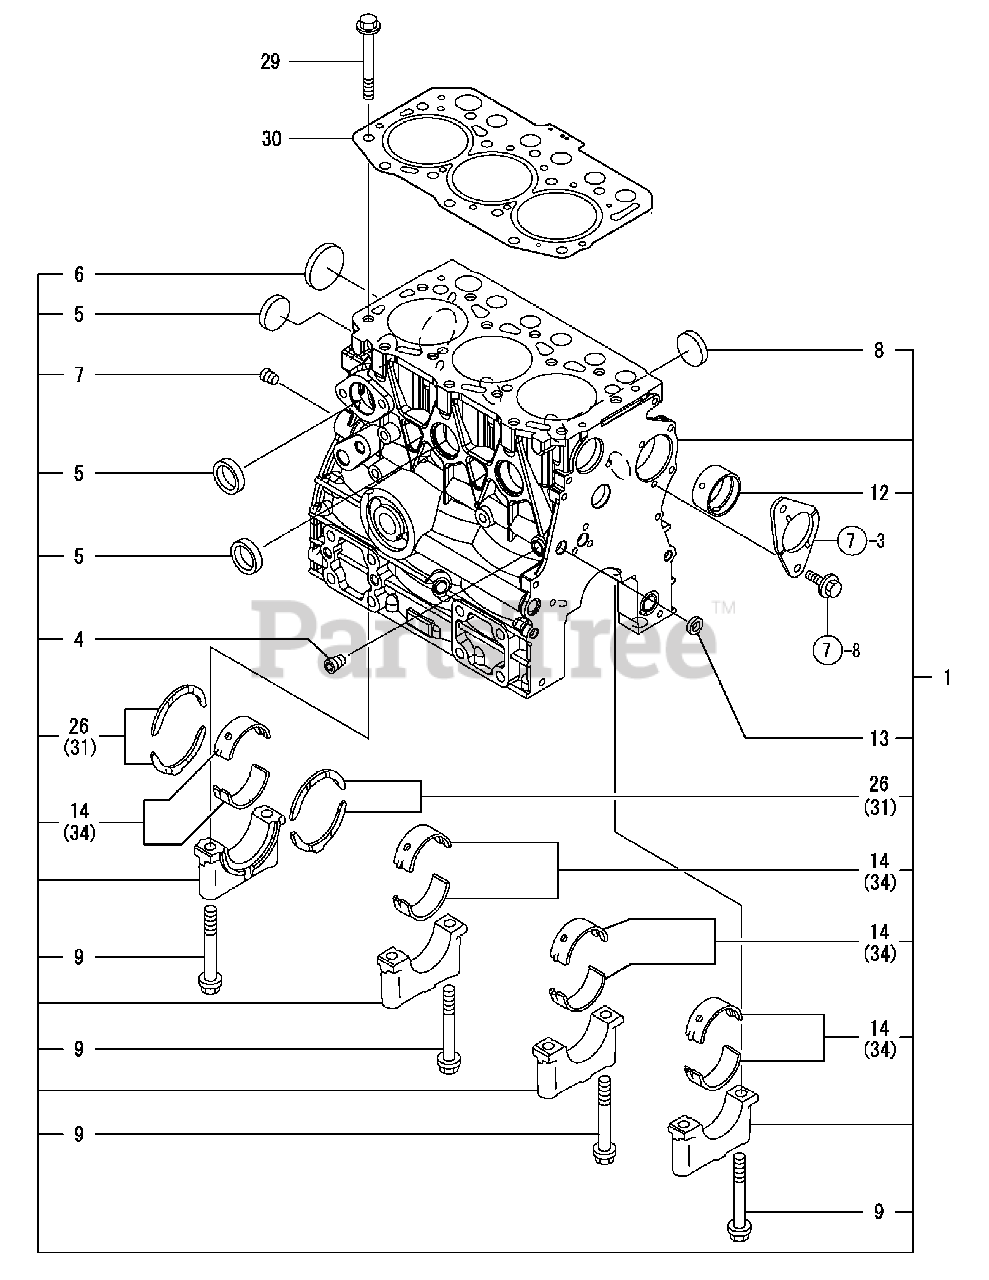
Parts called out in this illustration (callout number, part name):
1	BLOCK ASSY, CYLINDER
12	BUSH, CAMSHAFT
14	MAIN BEARING SET
26	BEARING, THRUST
29	BOLT, CYLINDER HEAD
30	GASKET, CYL.HEAD
31	BEARING,THRUST
34	MAIN METAL
